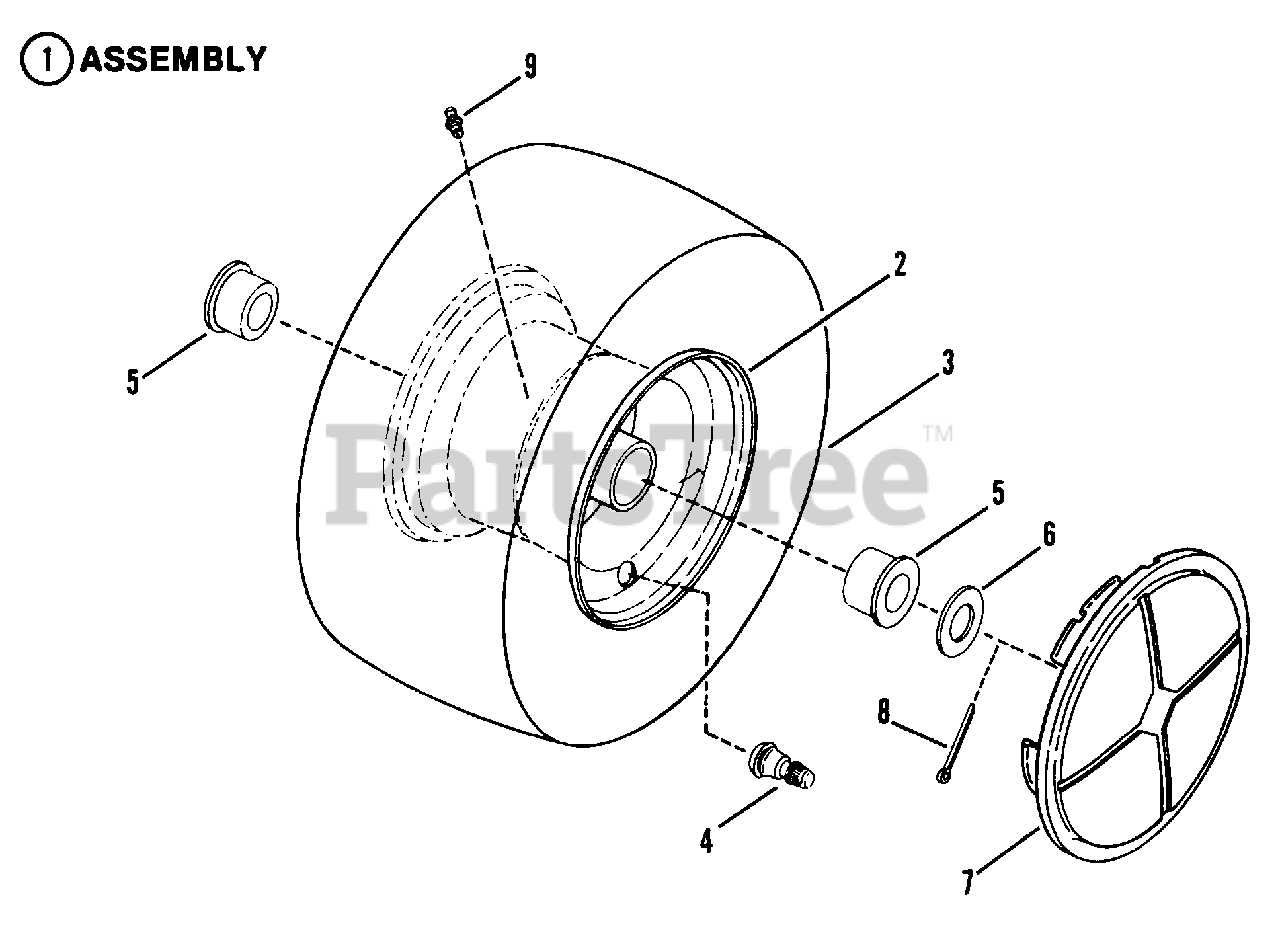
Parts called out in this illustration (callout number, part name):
1	ASSEMBLY, Front Tire & Rim 15x5.50-6.00
2	RIM, 6 x 4.50
3	TIRE, 15-5.50 x 6
4	VALVE, Air (Snap-in)
5	BEARING, Wheel Flanged PM .758 ID x 1.38 OD x 1.0 L
6	WASHER .77 x 1.5 x .06
7	WHEEL-COVER
8	COTTER-PIN 5/32 x 1 YZ
9	FITTING, Lube 1/4-28 Tapered Thread
